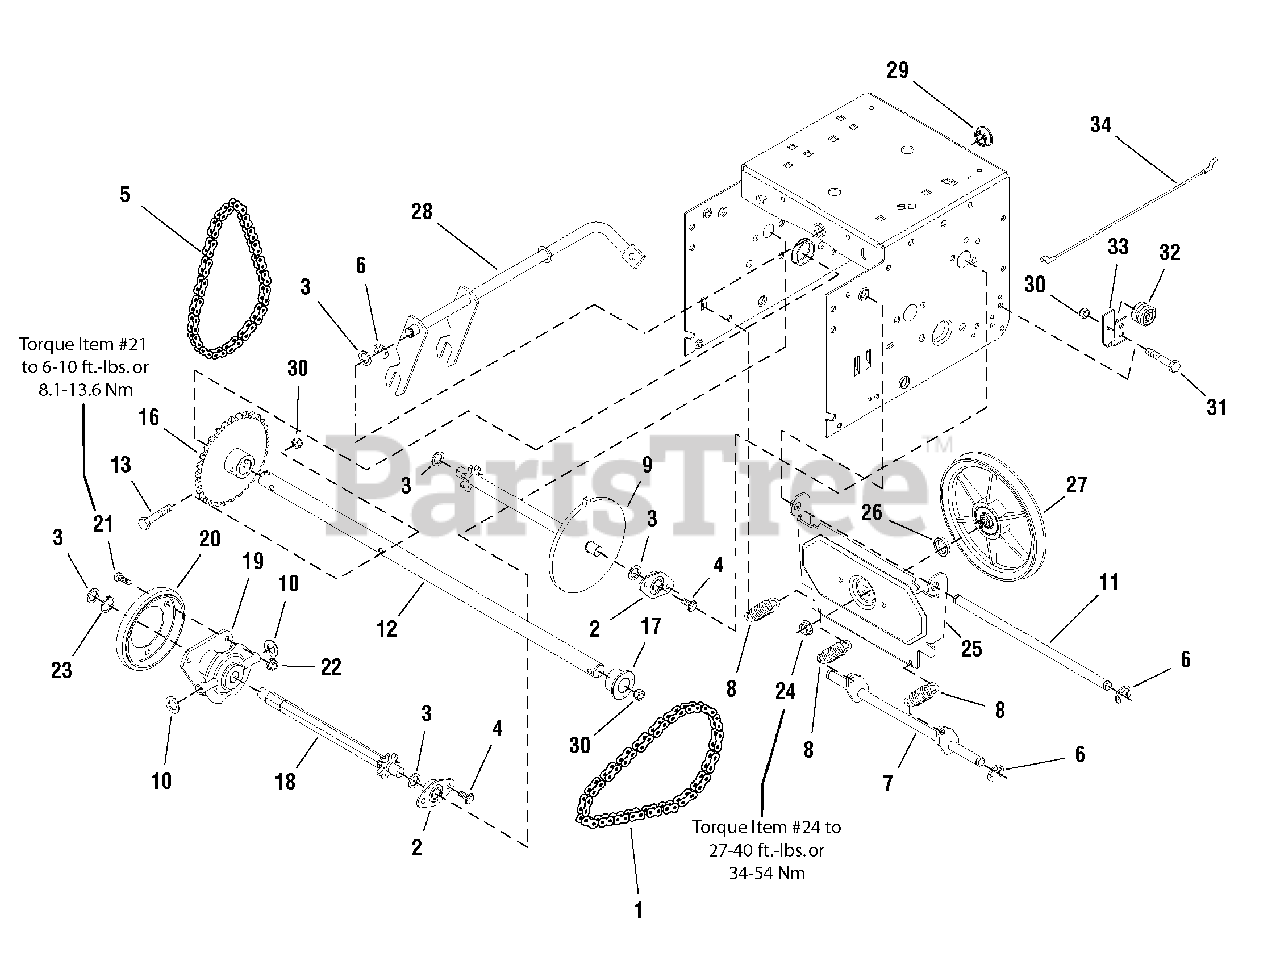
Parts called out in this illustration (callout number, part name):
1	CHAIN, Roller
2	RETAINER & BUSHING ASSEMBLY
4	SCREW, Hex Washer Head Taptite 5/16-18 x 1/2
5	CHAIN, Roller
6	RETAINER, Ring 7/16
7	SPRING LINK ASSEMBLY STANDARD
8	SPRING, Extension
9	SPROCKET, Set
10	WASHER, 1/2
11	AXLE, Swing Plate
12	AXLE
13	BOLT, Hex 1/4-20 x 1-3/4
16	SPROCKET, Axle
17	BEARING, Axle D-Hole
18	HEX SHAFT & SPROCKET ASSEMBLY
19	HUB, Friction Wheel & Bearing
20	WHEEL, Friction
21	CAPSCREW, Hex Head 1/4-20 x 5/8 G5
22	NUT, Hex KEPS 1/4-20
23	RING, Retaining, Extension
24	NUT, FlangeLock 38-24
25	PLATE, Swining
26	SPACER, Friction Pulley
27	FRICTION PULLEY ASSEMBLY
28	SPEED SELECT ASSEMBLY
29	BEARING, Flange
30	NUT, Hex Lock ESNA Light 1/4-20
31	CAPSCREW, Hex Head 1/4-20 x 1-1/2 G5
32	SPOOL CABLE, Auger Control
33	BRACKET, Cable Spool
34	CABLE, Front Drive Lower All
